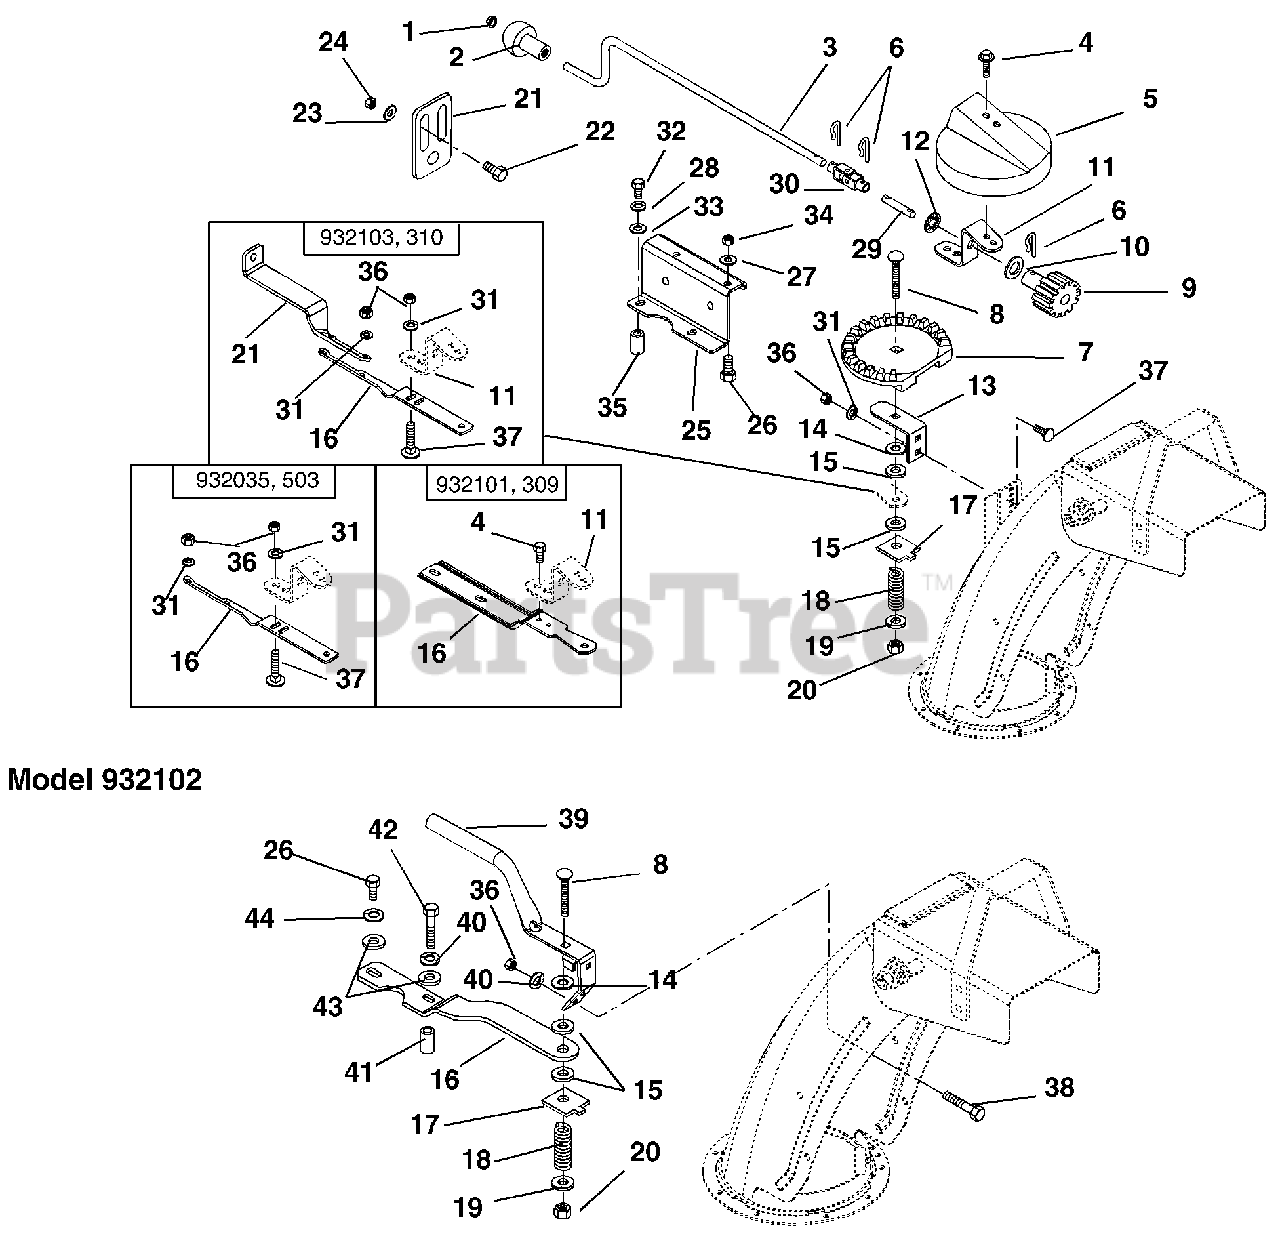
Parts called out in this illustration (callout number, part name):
1	CAP, 3/8 ROD YWZC
2	KNOB
3	CRANK, CHUTE
4	@SCR-TAP .25-20X.50 HWH TR YWZ
5	GEAR COVER
6	PIN, SPRING CLIP
7	CHUTE GEAR
8	@BLT-RDHDSQNK .38-16X2.50 G5YZ
8	@BLT-RDHDSQNK .38-16X2.25 G5YZ
9	PINION GEAR W/BRACKET
10	WSHR-FL-STL .630X1.005X.062 YZ
11	BRACKET-GEAR
12	PUSHNUT .625
13	GEAR STRAP
14	WSHR-FL-STL .380X1.50X.062 YWZ
14	@WSHR-FL-STL.563X1.38X.109YWZC
15	FRICTION WASHER
16	BRACKET, CHUTE SUPPORT
16	BRACE, CHUTE CONTROL
17	FRICTION PLATE
18	SG-COMP .187X.56X1.62
19	@WSHR-FL-STL.406X.812X.065 YWZ
20	@NUT-LK-CTR .38-16 YWZC
21	BRACKET, CHUTE CRANK SUPPORT
21	SUPPORT, CHUTE CRANK
22	@BLT-HEX .25-20X.50 GR5 YWZC
23	@WSHR-FL-STL.312X.734X.065 YWZ
24	@NUT-LK-CTR .25-20 YWZC
25	BRACKET, ENGINE
26	@BLT-HEX .31-18X.75 GR5 YWZC
27	@WSHR-FL-STL.312X.734X.065 YWZ
28	@WSHR-LK .31X.078 REG YWZC
29	PIN, CONNECTOR
30	UNIVERSAL JOINT ASS'Y
31	@WSHR-LK .25X.062 REG YWZC
32	@BLT-HEX .31-18X1.25 GR5 YWZC
33	@WSHR-FL-STL.344X.688X.065YWZC
34	@NUT-LK-CTR .31-18 YWZC
35	SPACER .322X.626X.50
36	@NUT-HEX .25-20 YWZC
37	@BLT-RDHDSQNK .25-20X.75 G5YZ
38	@BLT-HEX .25-20X.50 GR5 YWZC
39	HANDLE, COATED CHUTE
40	WSHR-LK .250X.077 HVY YWZC
41	SPACER .280X.625X.640
42	@BLT-HEX .25-20X1.50 GR5 YWZC
43	WSHR-FL-STL .328X.875X.062YWZC
44	WSHR-LK .312X.097 HVY YWZC
